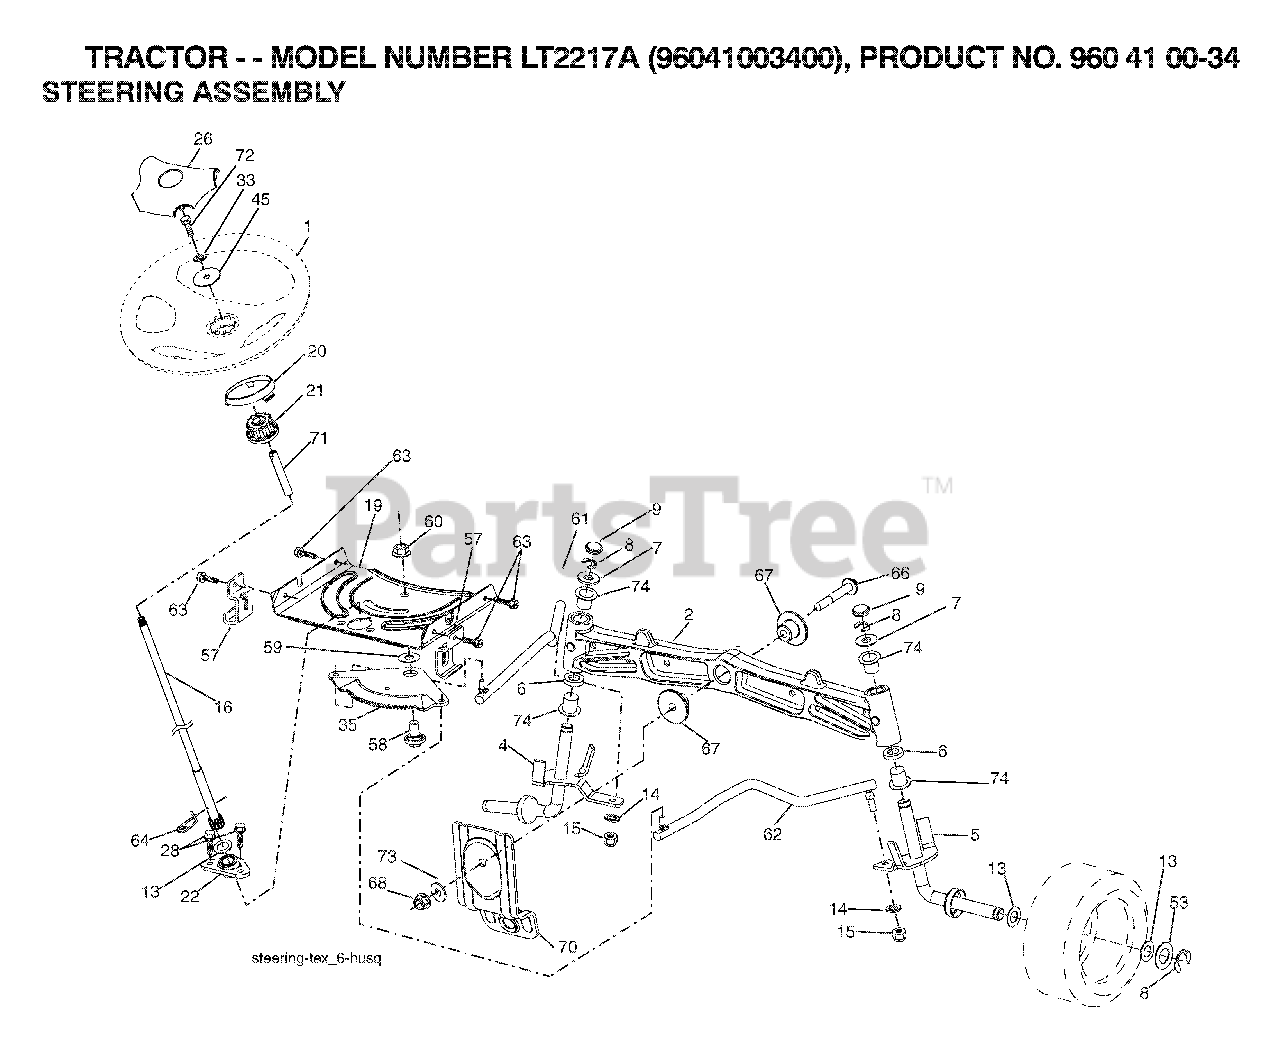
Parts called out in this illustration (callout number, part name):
1	WHEEL.STEERING.PREM.2.BLK
2	AXLE.HALF.ASM.WELDED
4	SPINDLE.WELDED.LH.15"TEX
5	SPINDLE.WELDED.RH.15"T
8	RING CLIP
9	CAP.SPINDLE
14	WASHER, LOCK 3/8
15	NUT CROWNLOCK 3/8-24
16	SHAFT STEERING
19	PLATE.STEER.DDL.NLT/NG
20	BOOT STEERING BLACK
21	ADAPTER, WHEEL STNG..
22	BUSHING.ASM.STEERING.A
26	INSERT.CAP.STRG.WH.BLACK
28	SCREW, 3/8-16X3/4
33	LOCKWASHER
35	GEAR.SECTOR.PLATE.DDL.
45	WASHER.11/32
53	WASHER.HARDENED
57	BRACKET.UPSTOP.TEX
58	BOLT.SHOULDER.SECTOR.P
59	WASHER.THURST.SECTOR.S
60	NUT FLANGE LOCK 5/8-11
61	DRAGLINK.LH.BALLSTUD.D
62	DRAGLINK.RH.BALLSTUD.D
63	SCREW
64	RETAINER.CLIP.SPRING.S
66	BOLT HEX FGHD 7/16-14 X 3 SERR
67	BUSHING.PM.FRONT AXLE
68	NUT.LOCK.FLANGE.7/16
70	BRKT.DECK.SUSPENSION.F
71	SHAFT EXTENSION STEERING
72	BOLT YT
73	WASHER.1.5X.505X.118
74	BRNG T
